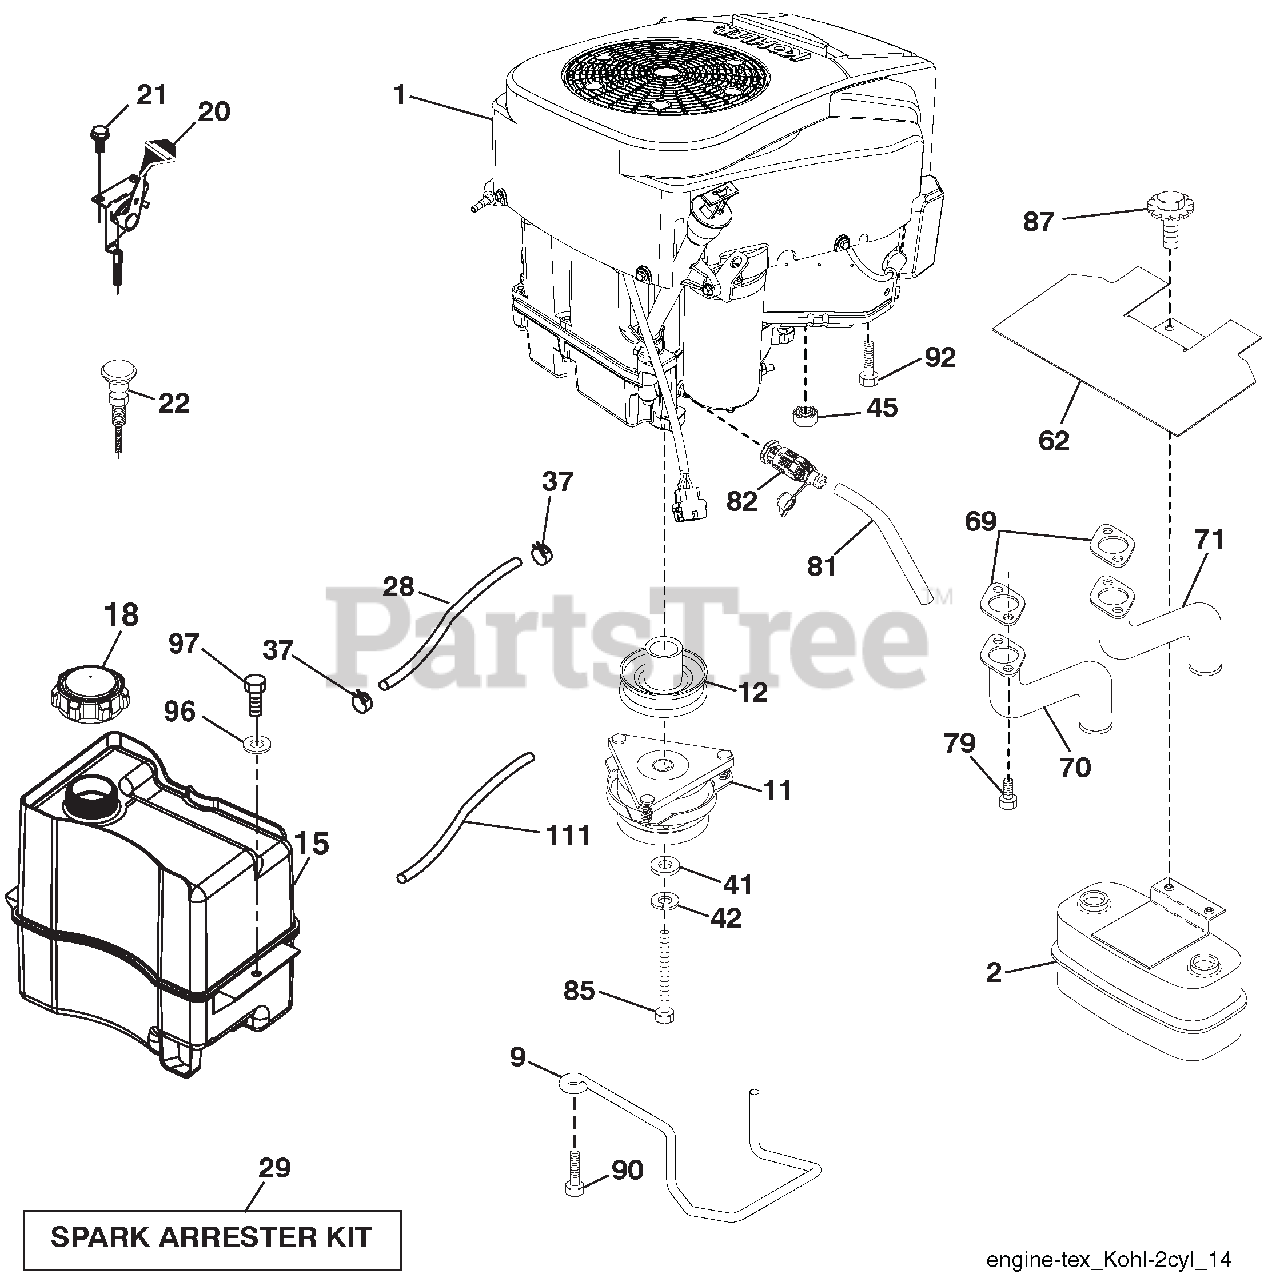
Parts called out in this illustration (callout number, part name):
1	KOHLER.ENGINE
1	(ORDER PARTS FROM ENGINE MANUFACTURER.)
2	MUFFLER ASM.TWIN.LO-TONE
9	KEEPER.BELT.ENGINE.4.25"NSTG
11	ELECTRIC CLUTCH
12	PULLEY.ENGINE.TUFFTORQE.1"CRK.
15	TANK.FUEL.2.5.GAL.
18	CAP FUEL
20	CONTROL.THROTTLE
22	CONTROL CHOKE
28	LINE.FUEL.20"
29	KIT.SPARK ARRESTOR(392390 B&S)
37	CLAMP.HOSE.BLK.
41	WASHER.1-1/2 ODX15/32 IDX.250
42	WASHER.LOCK.HVY HLCL.SPR.7/16
45	Nut, Keps Hex 1/4-20 unc
62	SHIELD.HEAT.MUFFLER.
70	PIPE.EXHAUST.LH.CV18/20
71	PIPE.EXHAUST.RH.CV18/20
79	SCREW.SOCKET HD.5/16-18 X .75
81	TUBE.DRAIN.OIL.EASY
82	VALVE OIL DRAIN
85	BOLT.HEX.7/16-20 X 3.75 X GR.
87	BOLT.5/16-18UNCX3/4 W/SEMS.BLK
90	SCREW.3/8-16X1.SMGML.TAP/R.BLK
92	SCREW.3/8-16 X 1.SMGML.TAP/R
96	WASHER.9/32 X 7/8 X 16GA.
97	SCREW.HEXWSH.THDROL.1/4-20X3/4
111	PURGE.LINE.CARB
